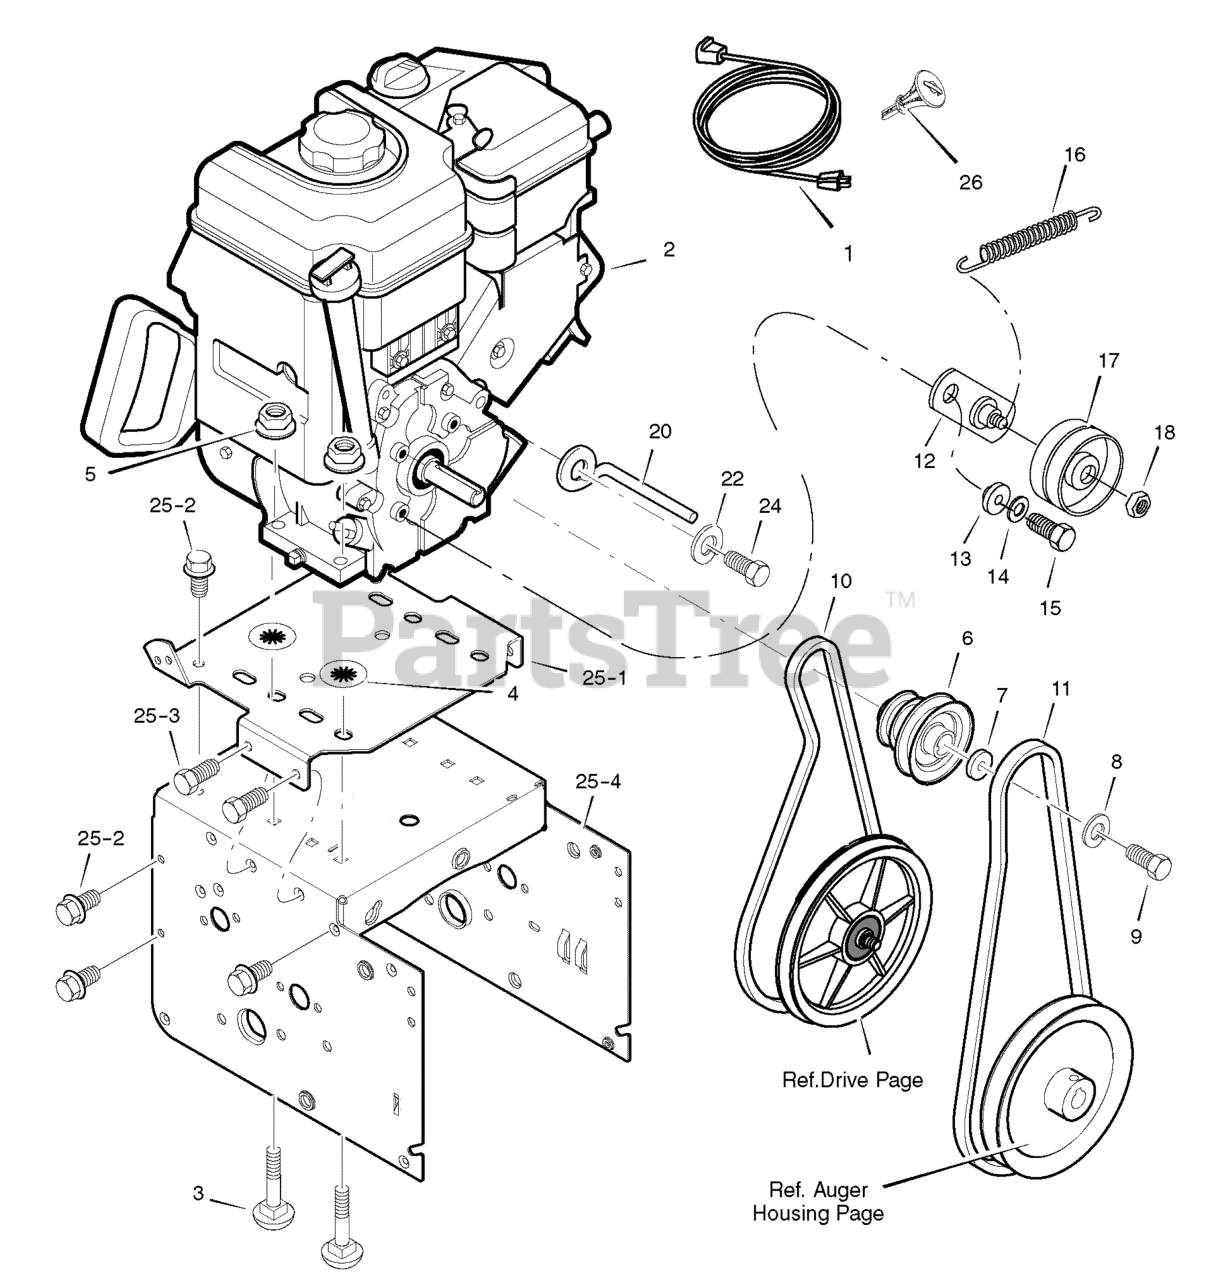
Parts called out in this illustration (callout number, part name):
1	CORD, STARTER
2	ENGINE
3	BOLT, CARRIAGE
4	RETAINER, PUSH
5	NUT
6	PULLEY, ENGINE
8	WASHER
10	V-BELT, 3L, 33.13
11	V-BELT, 4L, 38.35
12	BRACKET ASSEMBLY, IDLER
13	BUSHING, IDLER BRACKET
14	WASHER, SPLIT
15	SCREW 5/16-24 X 0.75
16	SPRING, IDLER TRACTION DRIVE
17	PULLEY, IDLER
18	NUT, JAM 3/8-16
20	GUIDE, ROD BELT
22	WASHER
25	FRAME ASSEMBLY
25-1	PLATE, ENGINE MOUNT
25-2	SCREW
25-4	MOTOR BOX
26	KEY, BRIGGS ENGINE
